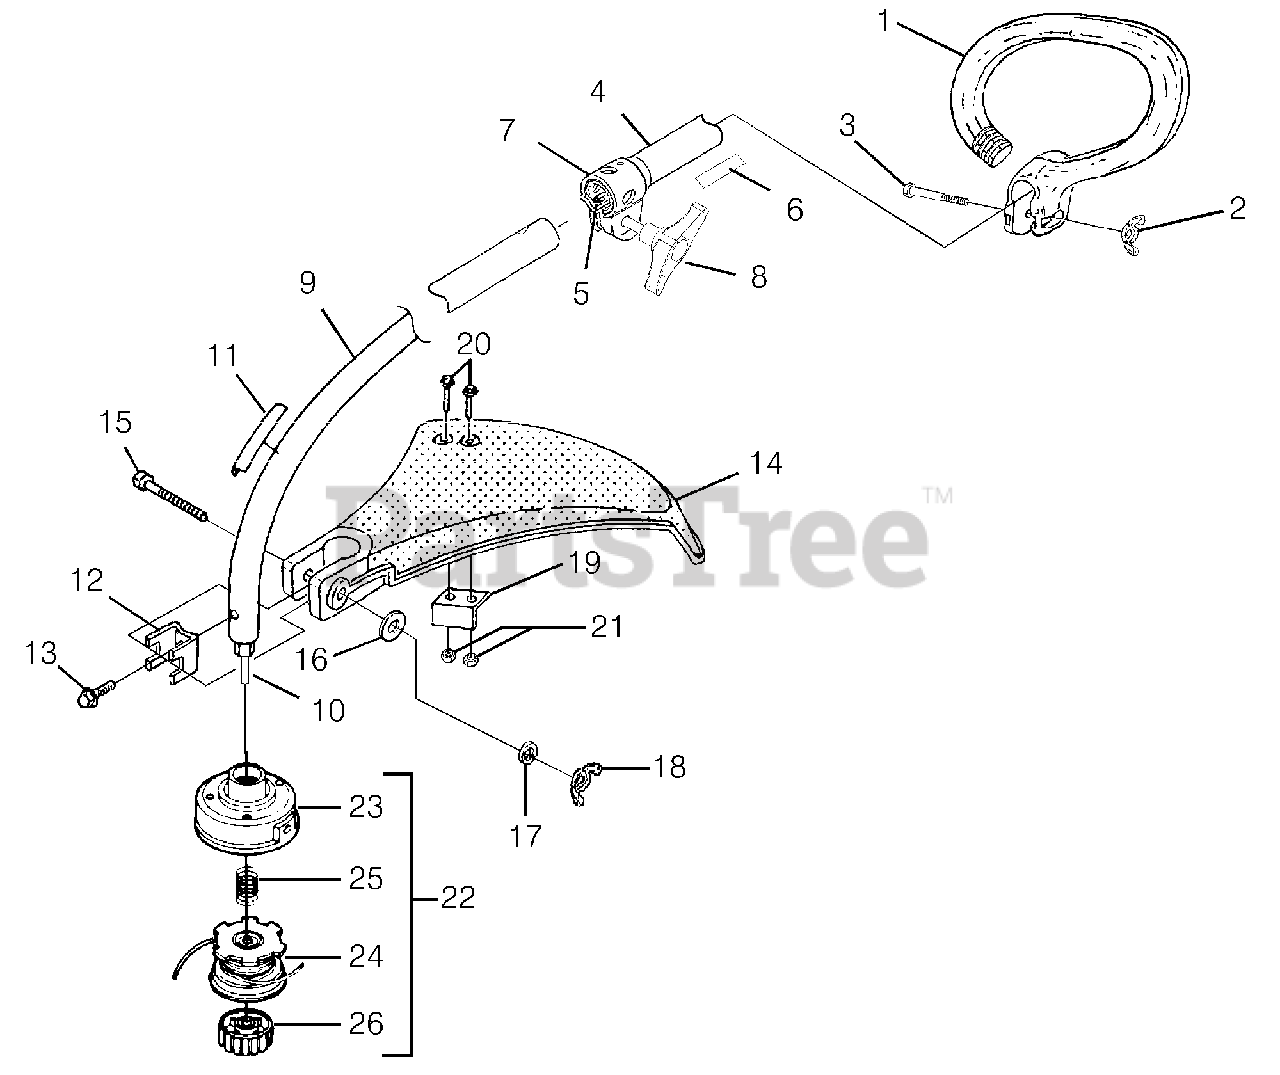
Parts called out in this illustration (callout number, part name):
1	HANDLE-Anti-Vibe
2	NUT-Wing, Washer Faced (1/4-20)
3	SCREW-Cap Hex Hd. (1/4-20 x 2")
4	DRIVESHAFT ASSY. (Upper)
5	FLEXSHAFT w/Collar & Liner
6	DECAL-Warning
7	COUPLER ASSEMBLY
8	KNOB
9	DRIVESHAFT HOUSING (Lower)
10	SHAFT-Flex
11	DECAL-Warning
12	CLAMP
13	SCREW-Sems Hex (10-24 X 3/8")
14	DEFLECTOR & BLADE KIT (55 Deg.)
15	SCREW-Cap Hex Hd. (1/4-20 X 2")
16	WASHER-Flat (1/4")
17	WASHER-Lock (1/4")
18	NUT-Wing, Washer Faced (1/4-20)
19	BLADE-Cut-Off
20	SCREW-Mech. Hex Hd. (10-24 X 7/8")
21	NUT-Hex (10-24)
22	STRINGHEAD-Complete (.080")
23	HOUSING & EYELET (Dual Line)
24	SPOOL & STRING (.080")
25	SPRING-Compression
26	RETAINER-Spool (R.H. Thread, Black)
